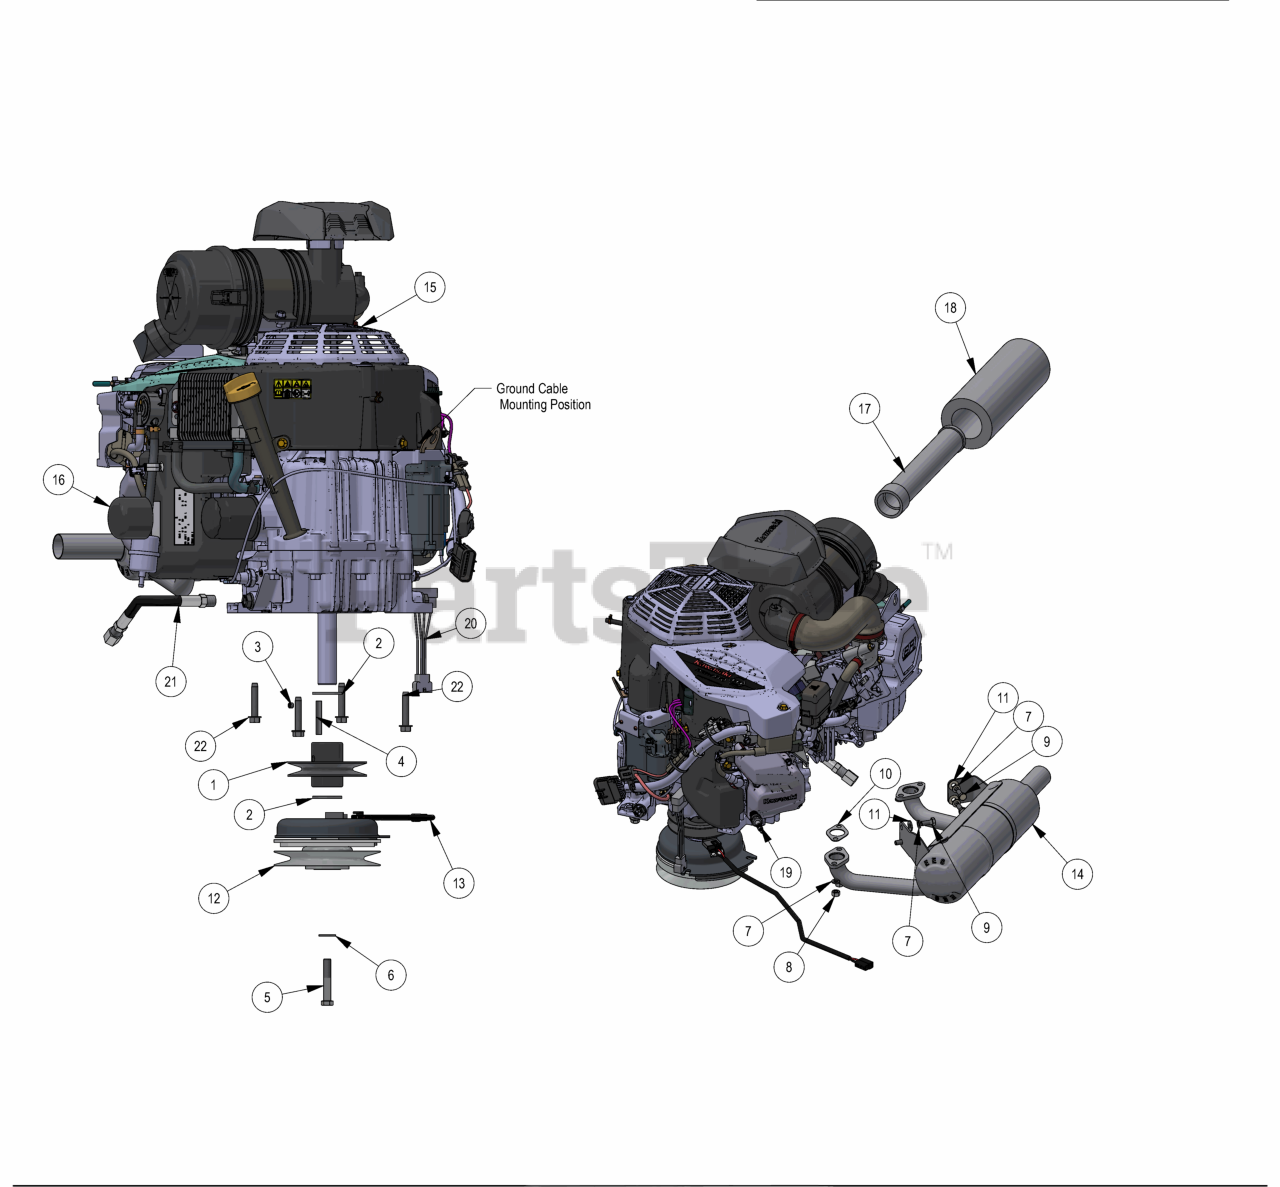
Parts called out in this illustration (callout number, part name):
1	4 3/4 Motor Pulley
2	1.140 ID X 1.750 OD X .132 THICK FLAT WASHER PLAIN
3	5/16-24 X 1/4 SOCKET SET SCREW (CUP PT) PLAIN
4	1/4 X 2 SQ MACHINERY KEY 1018 STL PLAIN
5	7/16-20 X 2-1/2 HEX CAP SCREW (GR.8) ZINC YELLOW
6	3/8 FLAT WASHER USS (1" OD) ZINC
7	5/16 SPLIT LOCKWASHER ZINC
8	M8-1.25 DIN 934 HEX NUT (CL.8) ZINC
9	M8-1.25 X 20MM DIN 933 HEX TAP BOLT (CL 8.8) ZINC
10	Exhaust Gasket
11	1/4 USS FLAT WASHER (3/4 OD) ZINC
12	Clutch Assembly
13	Clutch Pigtail
14	FXEVO Revolt Muffler
15	Kawasaki FX820V EVO
16	Oil Filter
17	Canister Air Filter- Inner
18	Canister Air Filter- Outer
19	Spark Plug
20	Harness Adaptor for Kawasaki EFI
21	Oil drain Hose
22	3/8-16 x 2 Hex/ Trilobe Horizontal Engine Bolt
